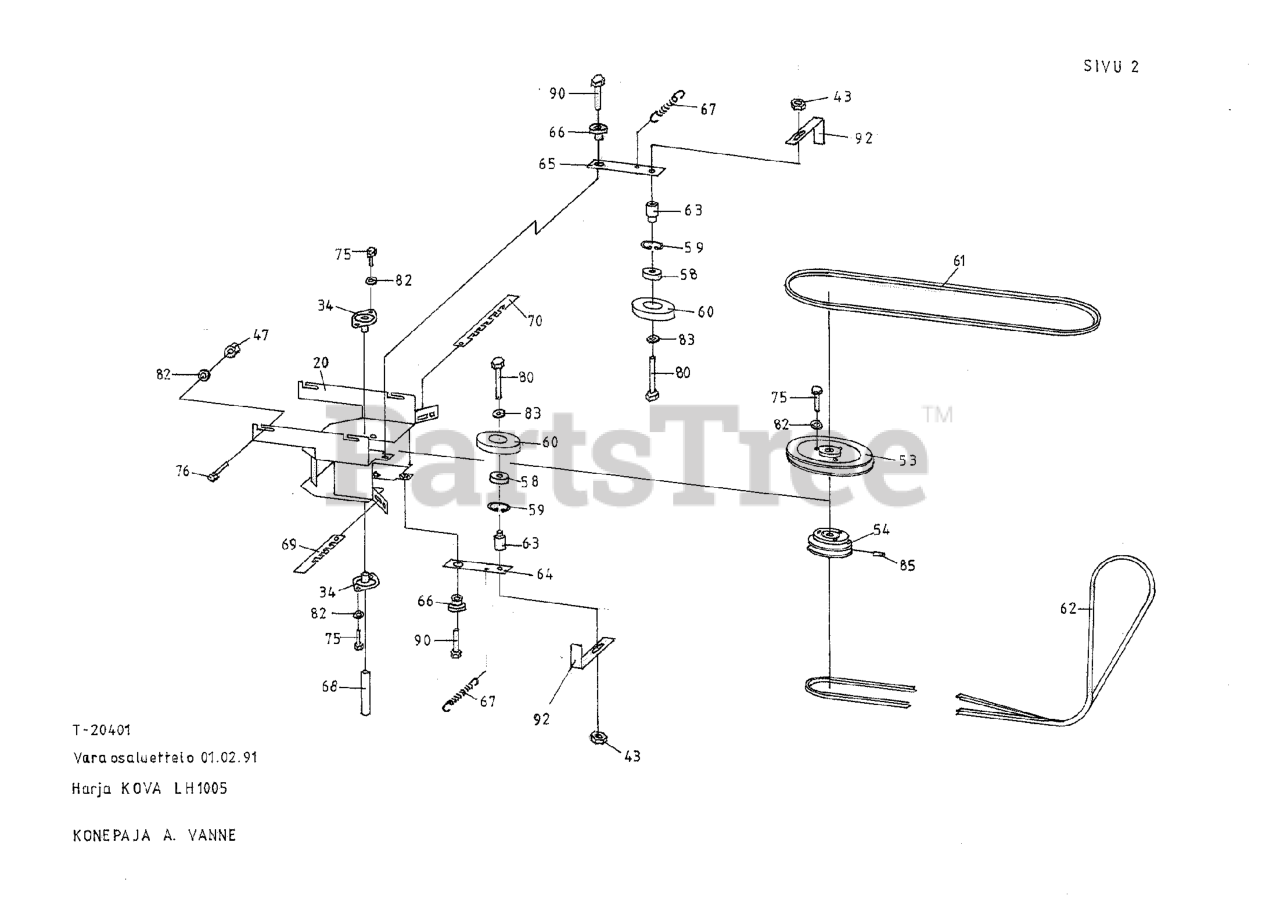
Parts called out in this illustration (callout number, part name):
4	BRUSHSEGMENT
5	WASHER BRUSHSEGMENT
7	BEARING UCFL 204
8	CHAINTIGHTNER
9	CHAINWHEEL
12	CHAINWHEEL
17	CHAINPROTECTOR
20	FRAME BRUSH
28	RETAINING RING
70	BELT TIGHTENER
92	BELT GUIDE
